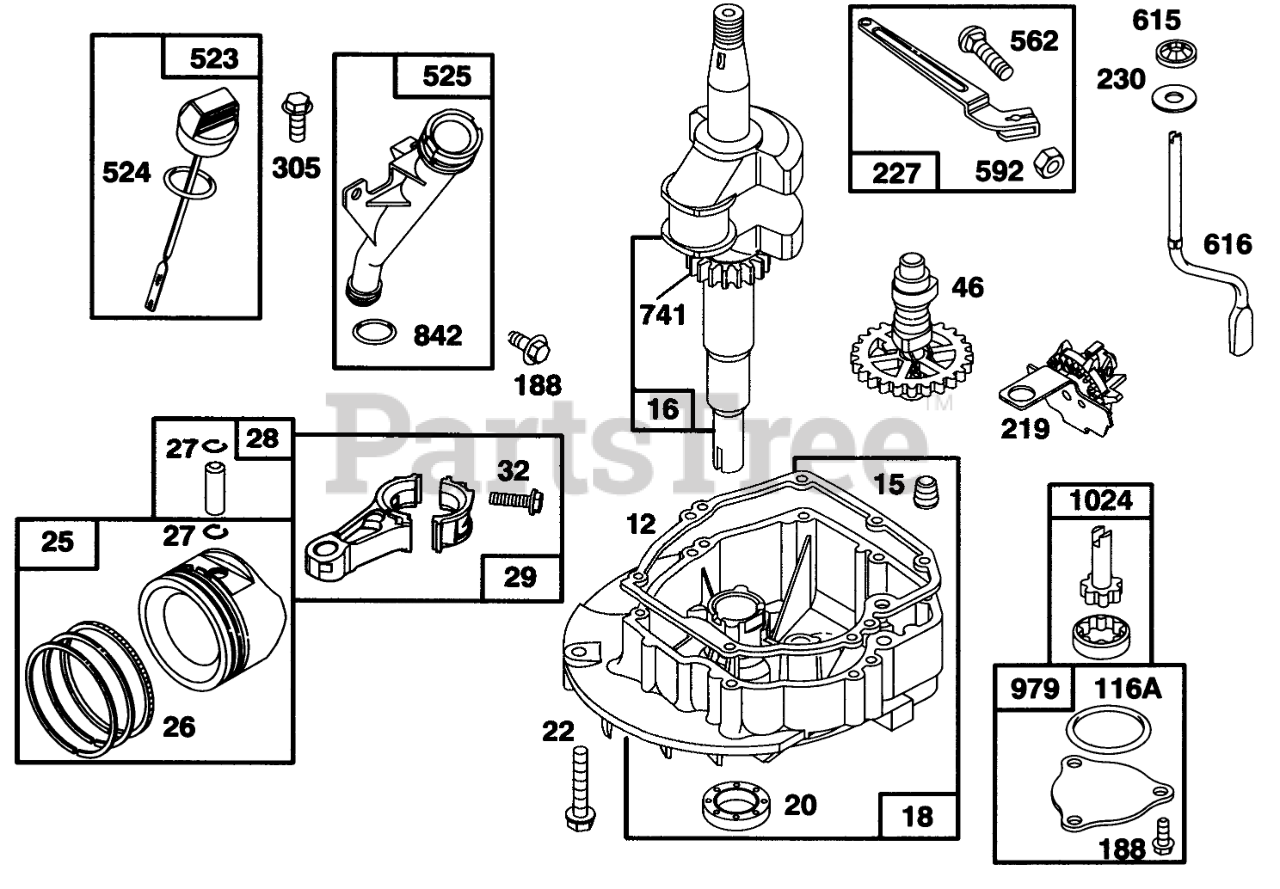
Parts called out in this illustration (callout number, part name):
12	ENGINE BASE GASKET
15	PIPE PLUG
16	CRANKSHAFT
18	ENGINE SUMP
20	SEAL-OIL
22	SCREW - ENGINE BASE
25	STD PISTON ASSEMBLY
26	STD RING SET
27	PISTON PIN LOCK
28	Pin Assy-Piston
29	CONNECTING ROD
32	Connecting Rod
46	CAM GEAR
116A	O RING SEAL
188	SCREW - SEM
219	GOVERNOR/OIL SLINGER
227	GOVERNOR LEVER ASSEMBLY
230	WASHER
305	SCREW - HEX HEAD
523	DIPSTICK-OIL
524	O-RING
525	OIL FILLER TUBE
562	GOVERNOR LEVER BOLT
592	HEX NUT
615	FASTENER
616	GOVERNOR CRANK
741	TIMING GEAR
842	O-RING
979	OIL PUMP COVER
1024	OIL PUMP
